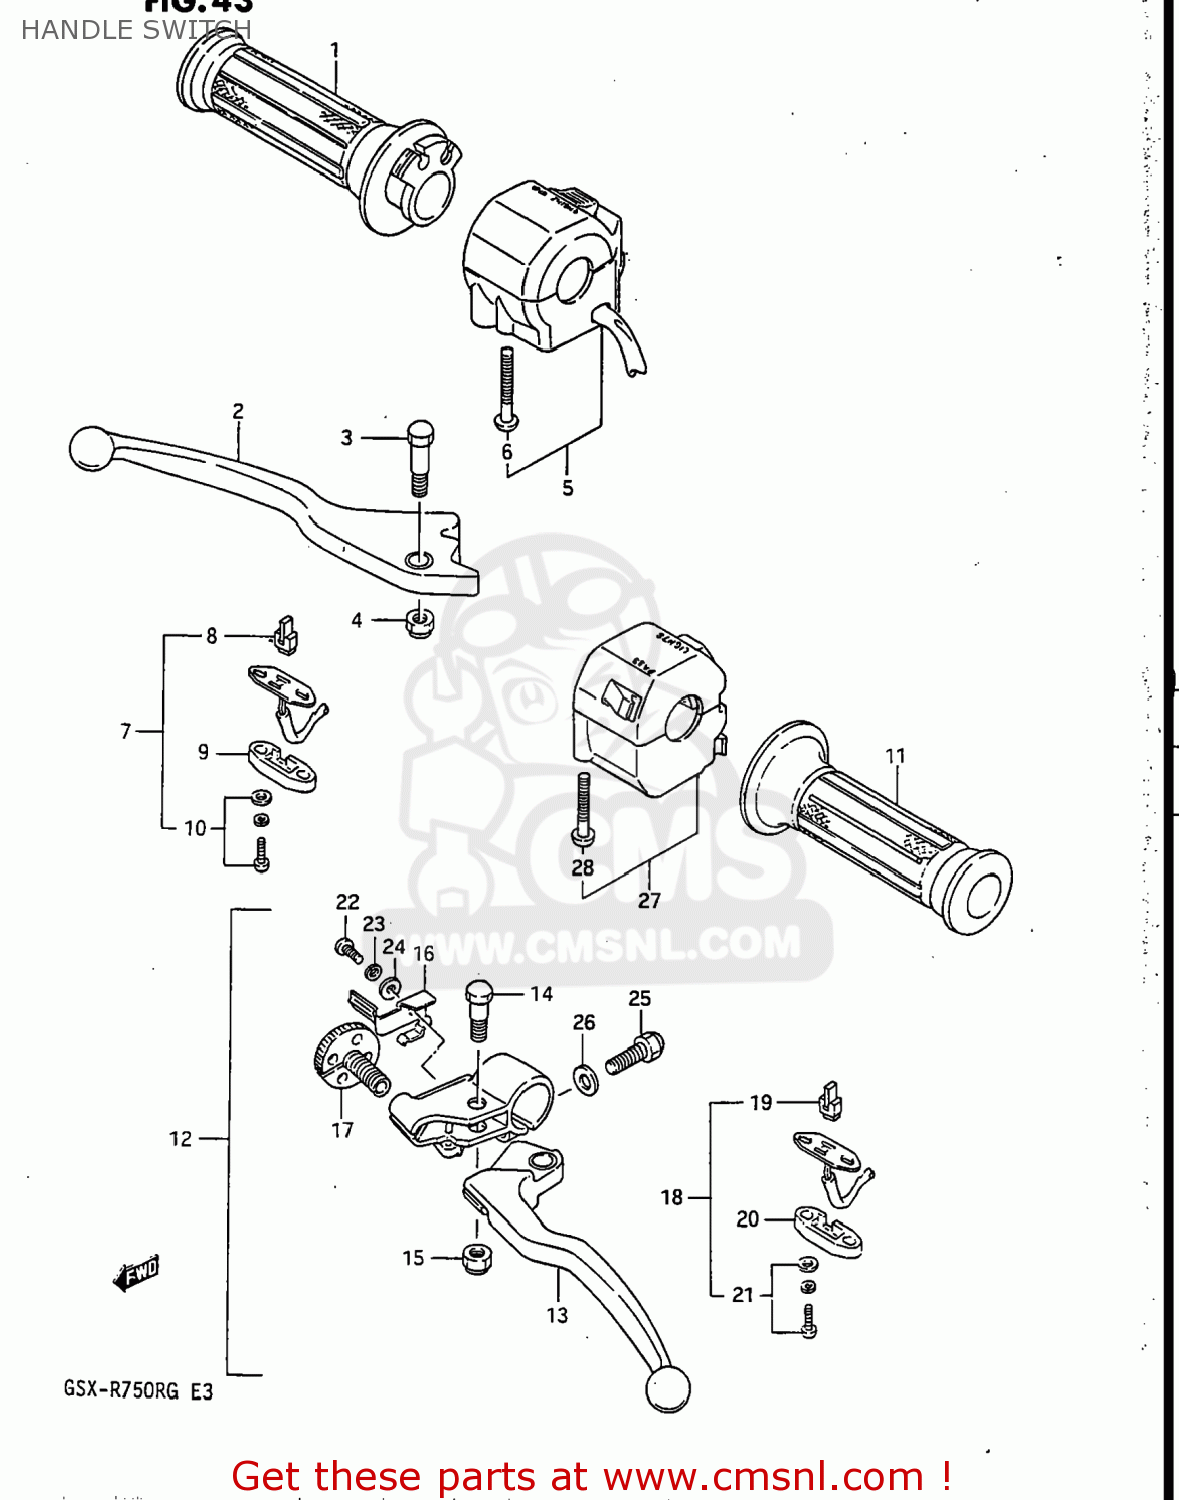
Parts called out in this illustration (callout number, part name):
1	GRIP,THROTTLE
2	LEVER,BRAKE
3	BOLT,LEVER
4	NUT
5	SWITCH ASSEMBLY,HANDLE,RIGHT
6	SCREW, 5X45
7	SWITCH ASSY,STOP
8	CONTACT,SWITCH
9	COVER,FR BK TERMINAL BASE
10	SCREW
11	GRIP,L
12	LEVER ASSEMBLY
13	LEVER,CLUTCH
14	BOLT,LEVER PIVOT
15	NUT
16	ADJUSTER,SPRING
17	ADJUSTER,LOCK
18	SWITCH ASSEMBLY,CLUTCH
19	CONTACT,SWITCH
20	COVER,FR BK TERMINAL BASE
21	SCREW
22	SCREW
23	LOCK WASHER
24	WASHER
25	BOLT
26	WASHER
27	SWITCH ASSEMBLY,HANDLE,LEFT
28	SCREW
